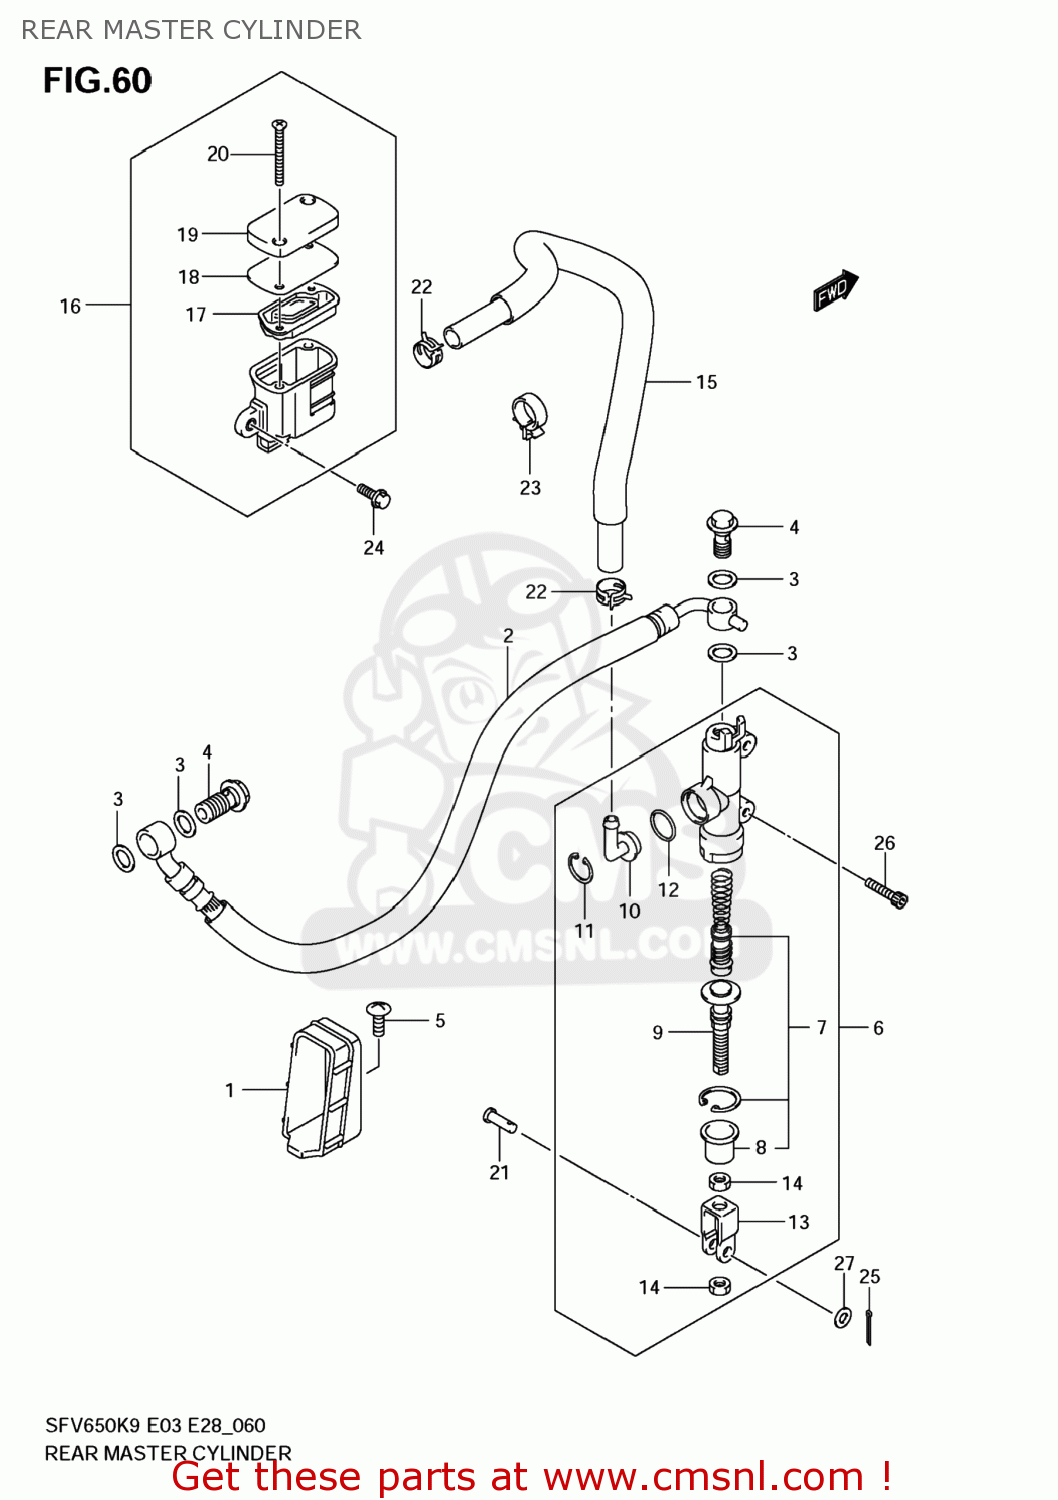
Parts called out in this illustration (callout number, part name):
1	GUIDE,RR BRAKE HOSE
2	HOSE,RR BRAKE
3	WASHER(10X15X1.5)
4	BOLT UNION
5	SCREW
6	CYLINDER ASSY,RR MASTER
7	PISTON/CUP SET
8	BOOT
9	ROD,PUSH
10	CONNECTOR
11	CIRCLIP
12	O RING
13	YOKE
14	NUT
15	HOSE,RR RESERVOIR TANK
16	TANK ASSY,RESERVOIR
17	DIAPHRAGM
18	PLATE,DIAPHRAGM
19	CAP
20	SCREW
21	PIN(6X18.2)
22	CLIP
23	CLAMP
24	BOLT
25	PIN
26	BOLT
27	WASHER
